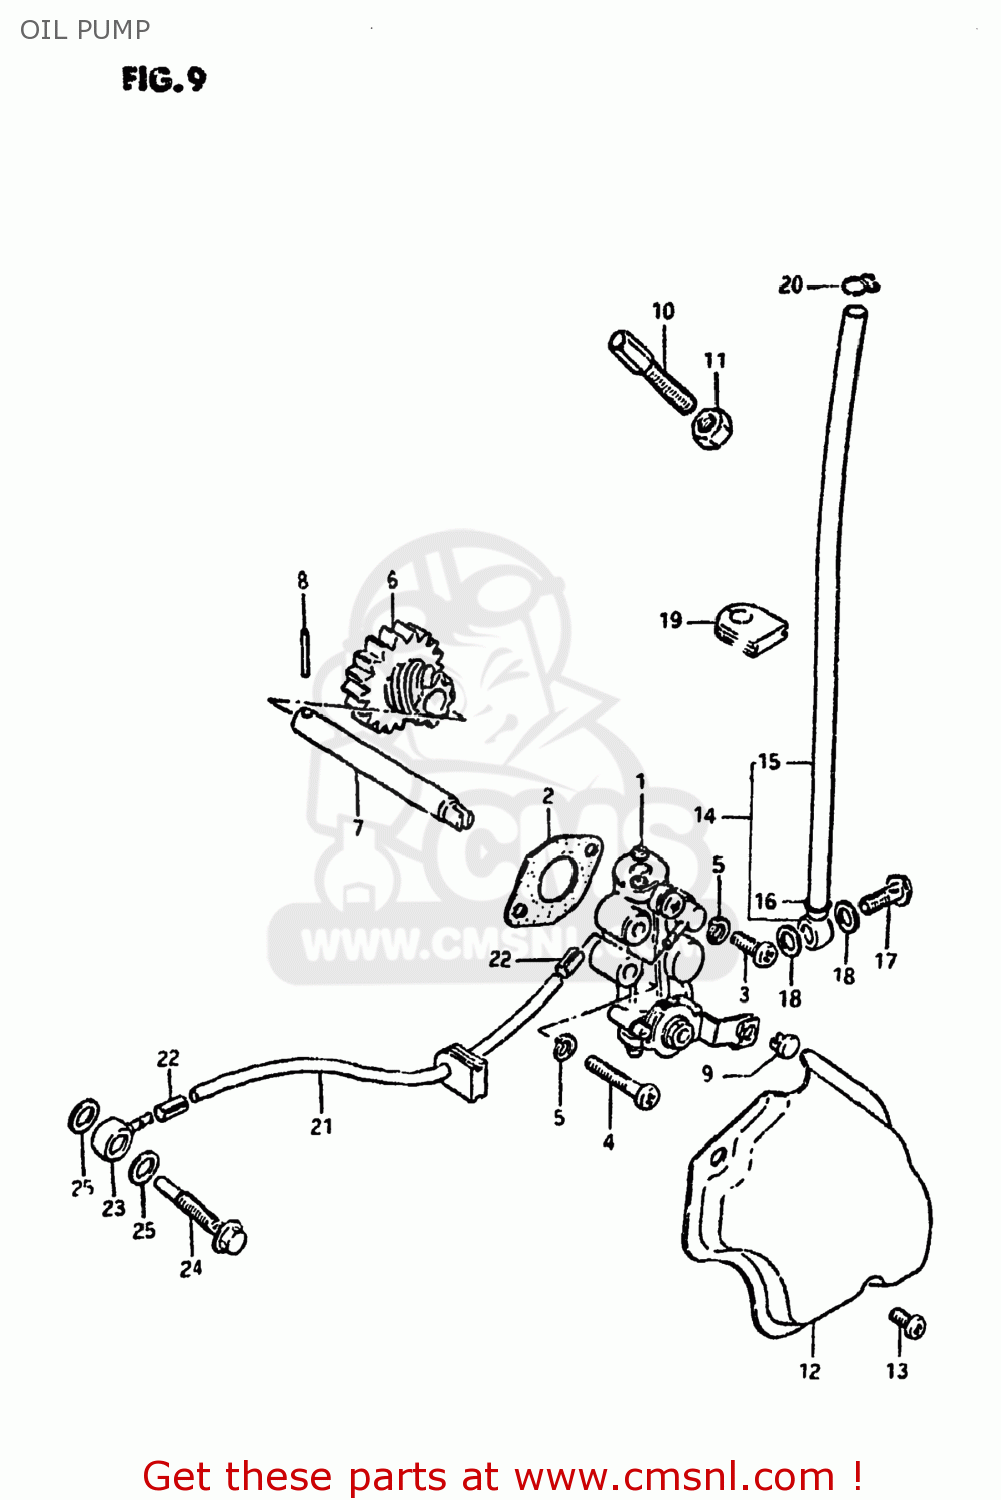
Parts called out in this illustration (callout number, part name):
1	PUMP ASSY,OIL
2	GASKET,OIL PUMP (MCA)
3	SCREW
4	SCREW
5	LOCK WASHER
6	GEAR,OIL PUMP DRIVE
7	SHAFT,OIL PUMP DRIVE
8	PIN(2.5X19.8)
9	TERMINAL,CABLE
10	BOLT
11	NUT
12	CAP,OIL PUMP INSPECTION
13	SCREW
14	HOSE,OIL NO.1
15	HOSE
16	CLIP
17	UNION BOLT
18	GASKET(6.2X11X1).2 (NAS)
19	GROMMET
20	CLIP
21	HOSE,OIL NO.2
22	CLIP
23	UNION
24	UNION
25	GASKET(6.2X11X1).2 (NAS)
